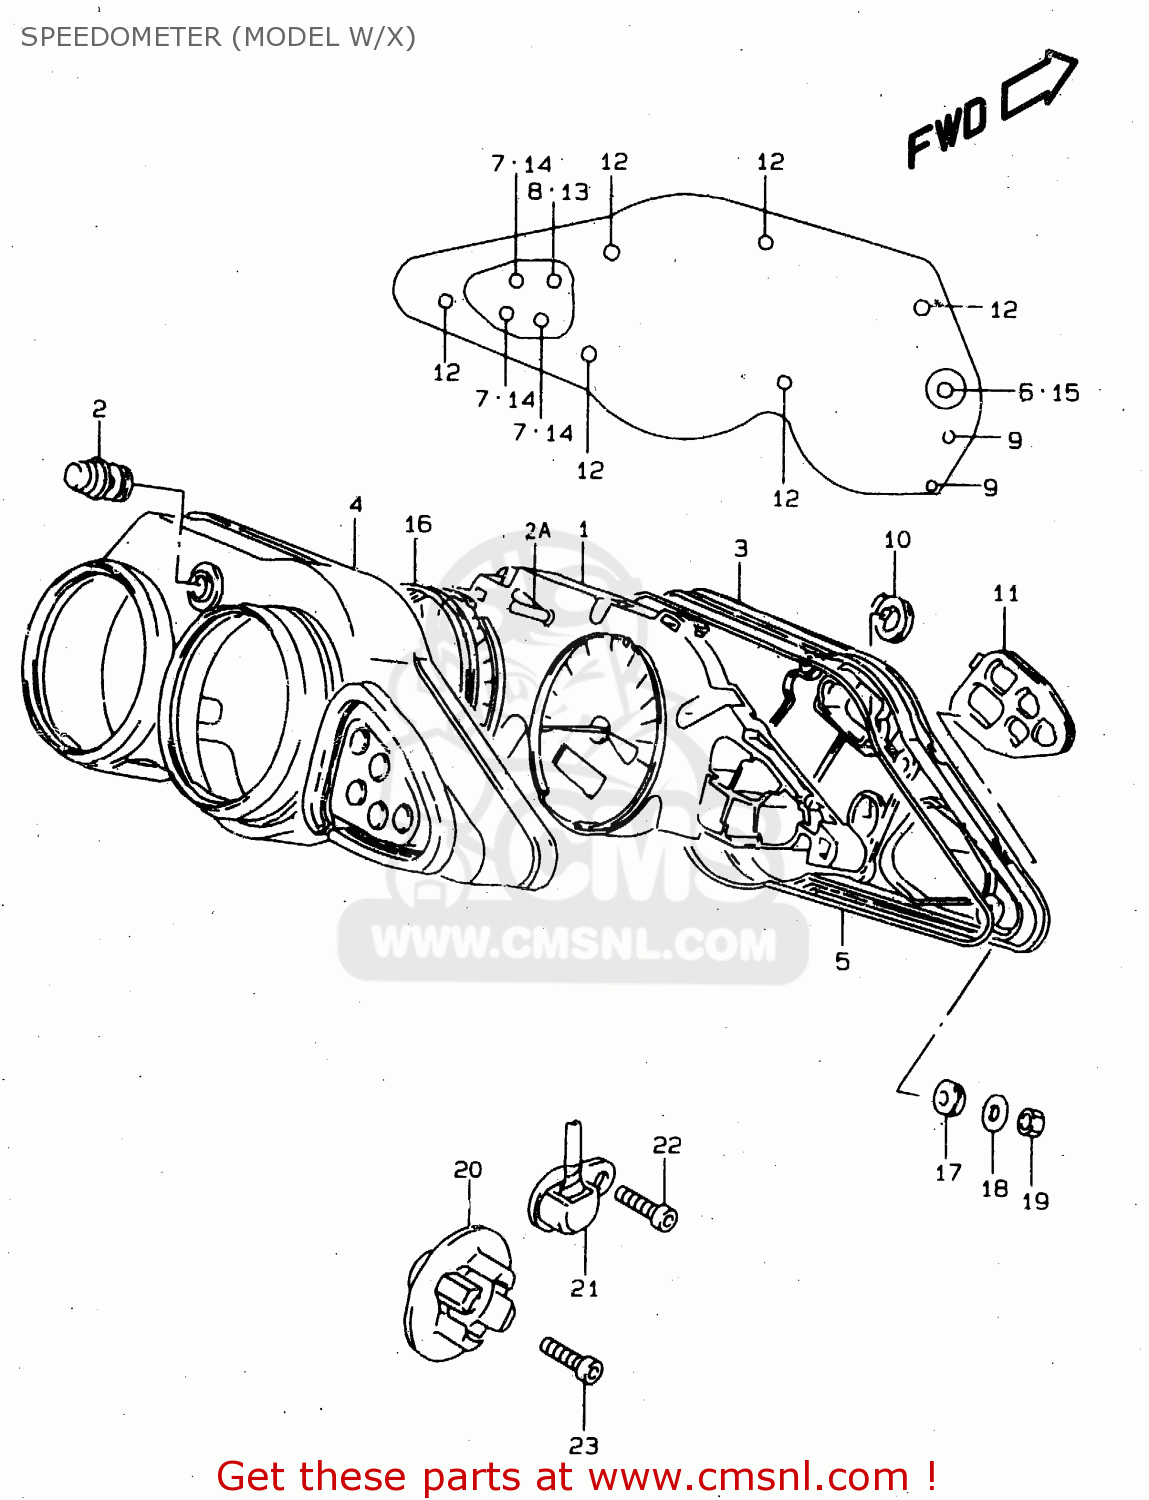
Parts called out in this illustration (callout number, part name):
1	SPEEDOMETER(KILO)
2	SWITCH,GUM
2A	LEVER
3	CASE ASSEMBLY
4	VISOR
5	GASKET (NAS)
6	SOCKET,BULB
7	SOCKET
8	SOCKET
9	SCREW(4X14)
10	BLIND,CAP
11	BLIND
12	SCREW
13	BULB(12V3W,WB371,T7)
14	BULB(12V1.7W,WB372,T7)
15	BULB(14V,0.84W)
16	CUSHION
17	CUSHION,METER
18	WASHER(5.5X16X1.2)
19	NUT
20	ROTOR,SPEED
21	SENSOR,SPEED
22	BOLT
23	BOLT
